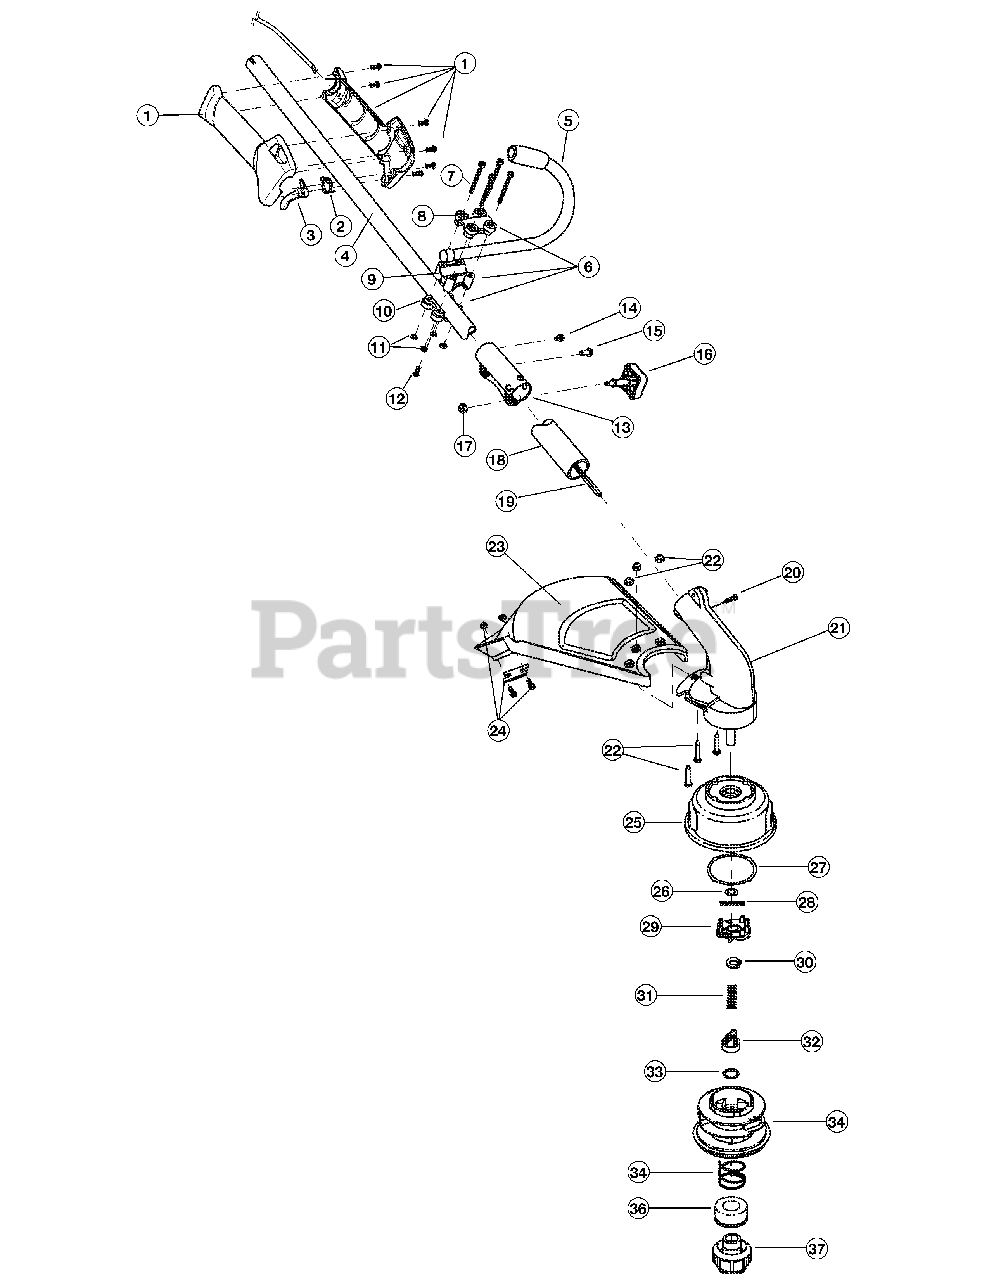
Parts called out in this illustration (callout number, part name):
1	Throttle HousingAssembly (includes 2 & 3)
2	Throttle Trigger Spring
3	Throttle Trigger
4	Upper Drive Shaft Housing Assembly
5	J-Handle Assembly
6	Handle Bracket Assembly (includes 7-12)
8	Upper Handle Clamp
9	Middle Handle Clamp
10	Lower Handle Clamp
12	Anti-Rotation Screw
13	Split Boom Coupler (includes 14-17)
16	Adjustment Knob (Includes 17)
17	Knob Retaining Nut
18	Lower Drive Shaft Housing Assembly
19	Lower Flexible Drive Shaft
20	Anti-Rotation Screw
21	Gearbox Assembly (includes 25-37)
22	Shield Mounting Hardware
23	Shield Assembly (includes 24)
24	Blade Assembly
25	Outer Spool Assembly (includes 26)
26	Retainer
27	Thrust Washer
28	Small Spring
29	Slider
32	Plunger
34	Inner Reel
35	Large Spring
36	Foam Seal
37	Bump Head Knob Assembly (Includes 35 & 36)
